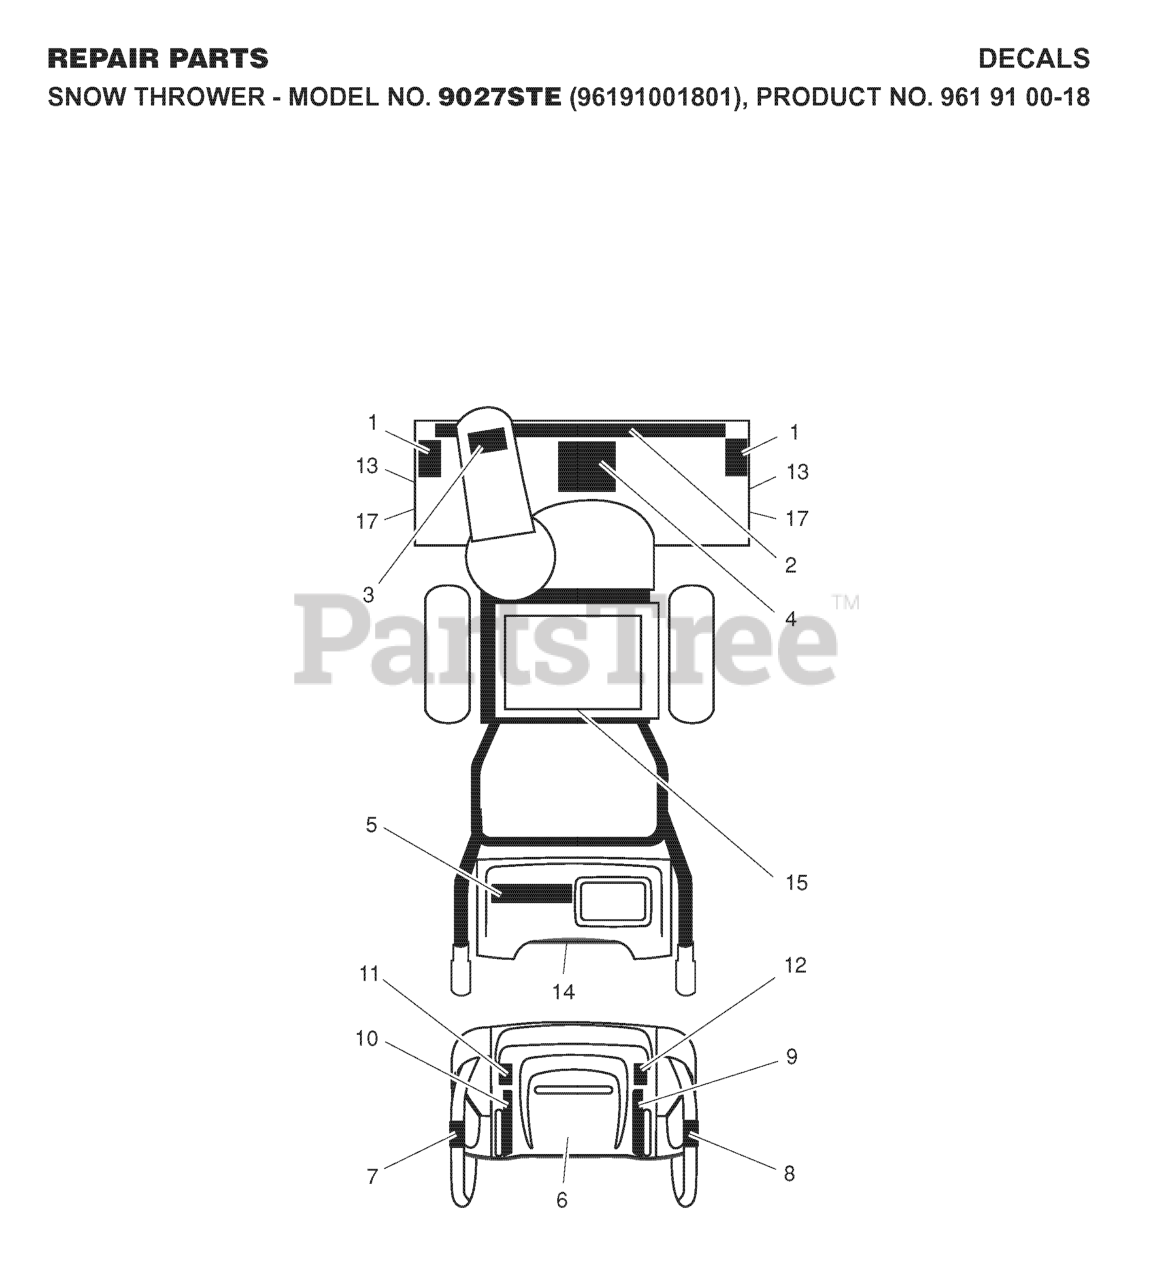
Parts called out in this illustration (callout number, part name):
1	DECAL.AUGER.SAFETY.
3	DECAL.CHUTE.SAFETY.
4	DECAL.AUGER."
6	DECAL.CONSOLE.INSTRUCTION
10	DECAL.REM.DEFLECTOR.LT
11	DECAL, LH TRIGGER
12	DECAL, RH TRIGGER
14	DECAL.NOISE.LEVEL.108DB/CE.INT
15	DECAL.BELT.GUARD.
17	DECAL, HUSQVARNA
